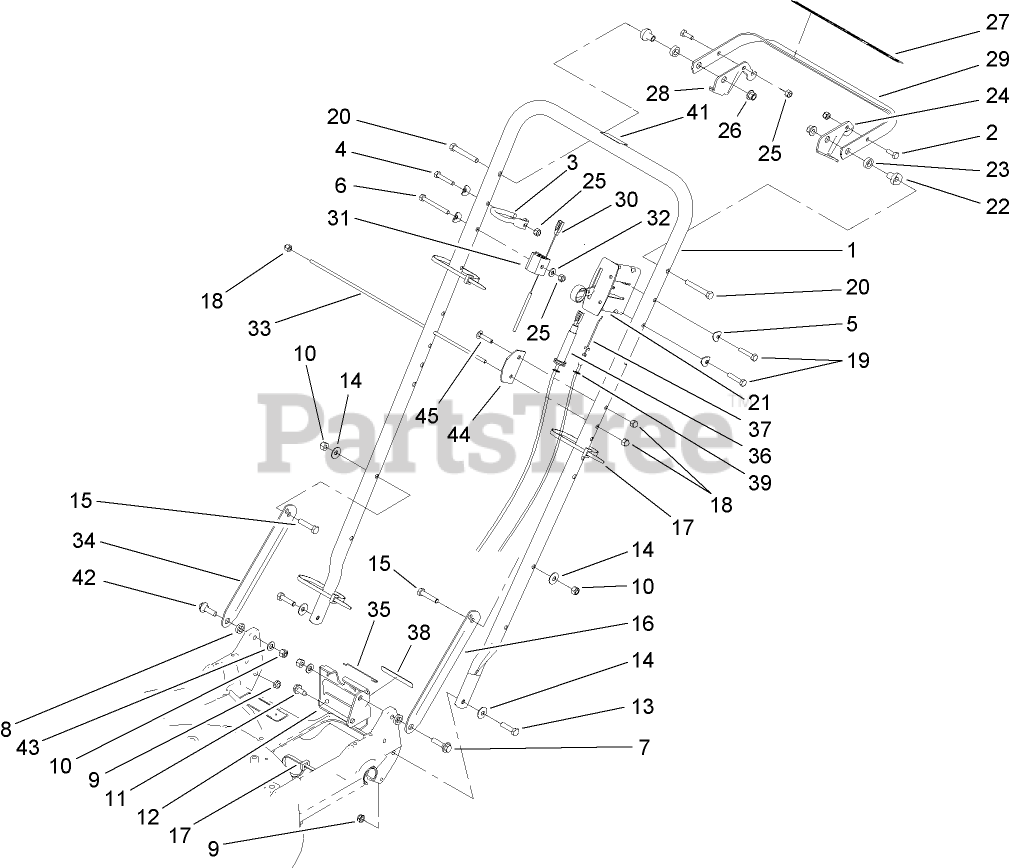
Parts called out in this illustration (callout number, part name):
2	SCREW-HH
3	GUIDE-ROPE
4	SCREW-HH
5	WASHER
6	SCREW-HH
7	SCREW-SHOULDER
8	SPACER
9	NUT-LOCK, NI
10	NUT-LOCK, NI
11	SCREW-HWHTF
12	BRACKET-ADJUSTMENT, TRACTION
13	SCREW-HH
14	WASHER-BELLEVILLE
15	SCREW-HH
16	LATCH-HANDLE, LH
17	TIE-CABLE
18	NUT-CAP
19	SCREW-HH
20	SCREW-HH
21	CONTROL-HEAD, THROTTLE
22	SPACER-SUPPORT
23	SPACER-NYLON
24	LEVER-CONTROL
25	NUT-LOCK, NI
26	NUT-LOCK, NI
27	DECAL-TRACTION
28	LEVER-CONTROL
29	BAR-CONTROL
30	CABLE-BRAKE
31	SUPPORT-CABLE
32	WASHER-FLAT
33	ROD-SUPPORT, BAG
34	LATCH-HANDLE, RH
35	RETAINER-CABLE
36	CABLE-TRACTION
37	THROTTLE CABLE ASM
38	DECAL-POSITION, GEAR
39	E-RING
41	DECAL-PROTECTION, EAR
42	SCREW-SHOULDER
43	WASHER-PLAIN
44	PLATE-ALIGNING, BAG
45	SCREW-CARR
